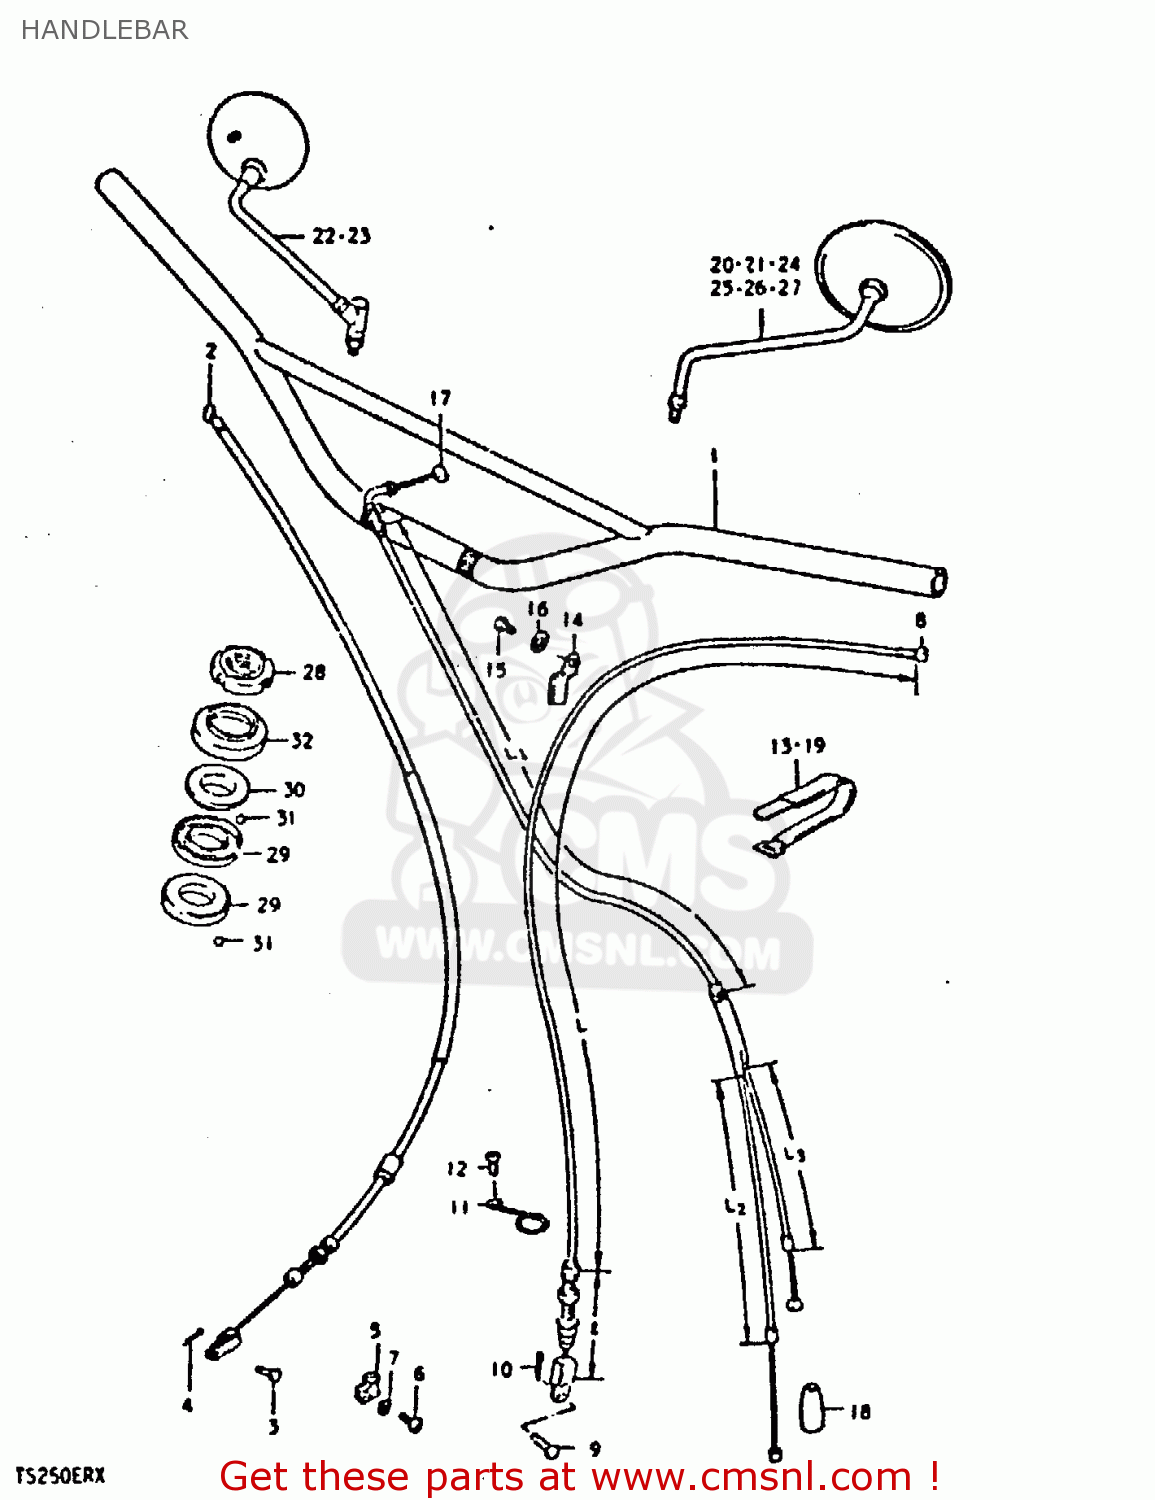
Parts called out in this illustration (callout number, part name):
1	HANDLEBAR (CHAMPAGE GOLD)
2	CABLE ASSY,FR BRAKE
3	PIN(L:17.5)
4	PIN
5	GUIDE,CABLE
6	SCREW
7	LOCK WASHER
8	CABLE ASSY,CLUTCH
9	PIN(L:15)
10	PIN
11	CLIP
12	SCREW
13	CLAMP
14	CLAMP
15	SCREW 6X12
16	WASHER
17	CABLE ASSEMBLY,THROTTLE
18	SEAL,DUST(7X18X30)
19	CLAMP
22	MIRROR ASSY,RH
28	NUT,STEERING STEM(25X44X10)
29	LACE,STEERING INNER LWR
30	LACE,STEERING OUTER UPR
31	BALL
32	DUST SEAL,STEERING UPR
